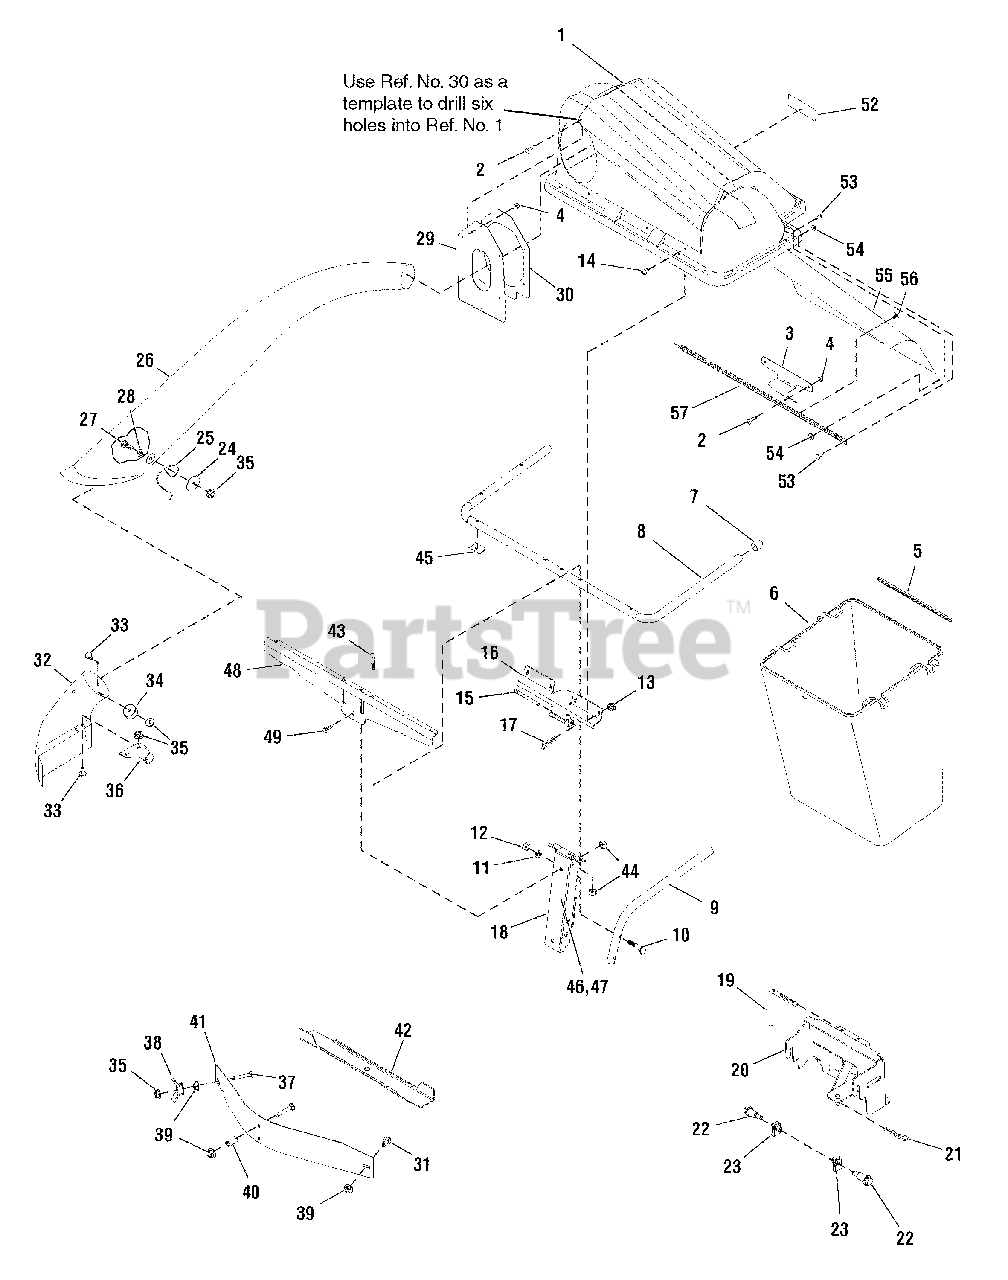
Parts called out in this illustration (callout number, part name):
1	COVER ASSEMBLY, with Decal
2	SCREW, 10 - 24 x 3/4
4	NUT, 10 - 24, ESNA Lock
5	EDGING, 13-1/8 Long
6	BAG ASSEMBLY, Twin
10	SCREW, 5/16 - 24, Curve
11	LOCKWASHER, 5/16
12	NUT, 5/16 - 24, Hex
13	NUT, 1/4 - 20, Keps Lock
14	SCREW, 1/4 - 20 x 1/2
15	PIN, Cover Hinge
17	PIN, Hair
18	CHANNEL ASSEMBLY
19	PIN, Channel Mount
20	MOUNT ASSEMBLY, Channel
21	PIN, Hair, 1/8 x 2-9/16
22	BOLT, Shoulder, 5/16 - 18
23	NUT, 5/16 - 18, Speed
25	LATCH, Wire Form
26	TUBE, Discharge
27	SCREW, 5/16 - 18 x 3/4
29	SEAL, Rubber
30	PLATE, Seal
31	BOLT, Carriage, 5/16 - 18 x 3/4
33	SCREW, 5/16 - 18 x 3/4
34	WASHER, Special
35	NUT, 5/16 - 18, Centerlock Flange
36	BRACKET, Boot Mount
37	BOLT, Carriage, 5/16 - 18 x 2
38	WINGNUT ASSEMBLY
39	NUT, Whizlock, 5/16 - 18
41	BAFFLE, 38"
42	BLADE, 38" Hi-Lift
43	BOLT, Carriage, 5/16 - 18 x 1-3/4
44	NUT, 5/16 - 18 ESNA
45	CLAMP, Saddle
46	ID LABEL/SERIAL PLATE
47	OVERLAY, Mylar
48	BRACE STIFFENER
49	CAPSCREW, 5/16 - 18 x 3/4
52	DECAL, Cover Warning
53	RIVET, Pop, 3/16
54	WASHER, Rivet, 3/16
55	SCREEN, Twin Cover
56	FASTENERS, Push, 1/4 x 1/2
57	SCREEN SUPPORT, Twin
58	INSTRUCTION MANUAL
